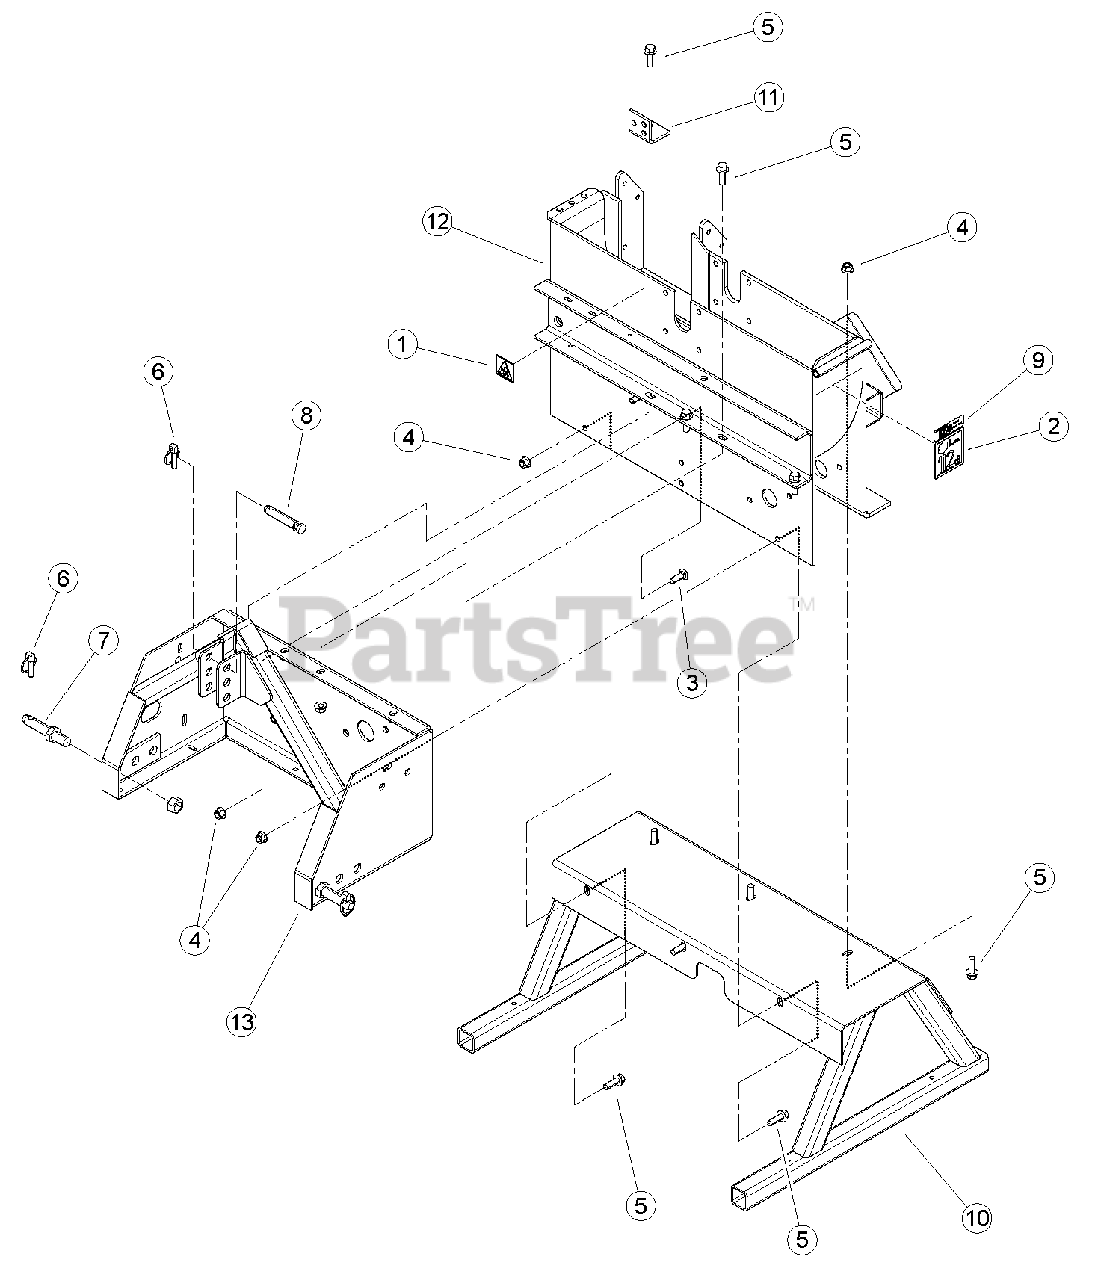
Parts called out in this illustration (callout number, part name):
1	DECAL, SHIELD DANGER ISO
2	DECAL, 112 DB (CE COMPLIANT ONLY)
3	BOLT, 1/2 X 1-1/2" GR5 ZP CRG
4	NUT, 1/2-13 NYLOCK FLANGE
5	BOLT, 1/2-13 X 1-1/2 GR5 FLANGE NC
6	PIN, 7/16 X 1-3/4 LYNCH
7	PIN, LIFT ARM 7/8 X 5" LG
8	PIN, TOP LINK 3/4 X 4-1/2" LG
9	DECAL, ATLANTIC BRIDGE LTD INFO (CE COMPLIANT ONLY)
10	WELDMENT, PTO STAND
11	ANGLE, LOWER SHOCK
12	WELDMENT, CHIPPER BOTTOM
13	WELDMENT, HITCH SUPPORT
